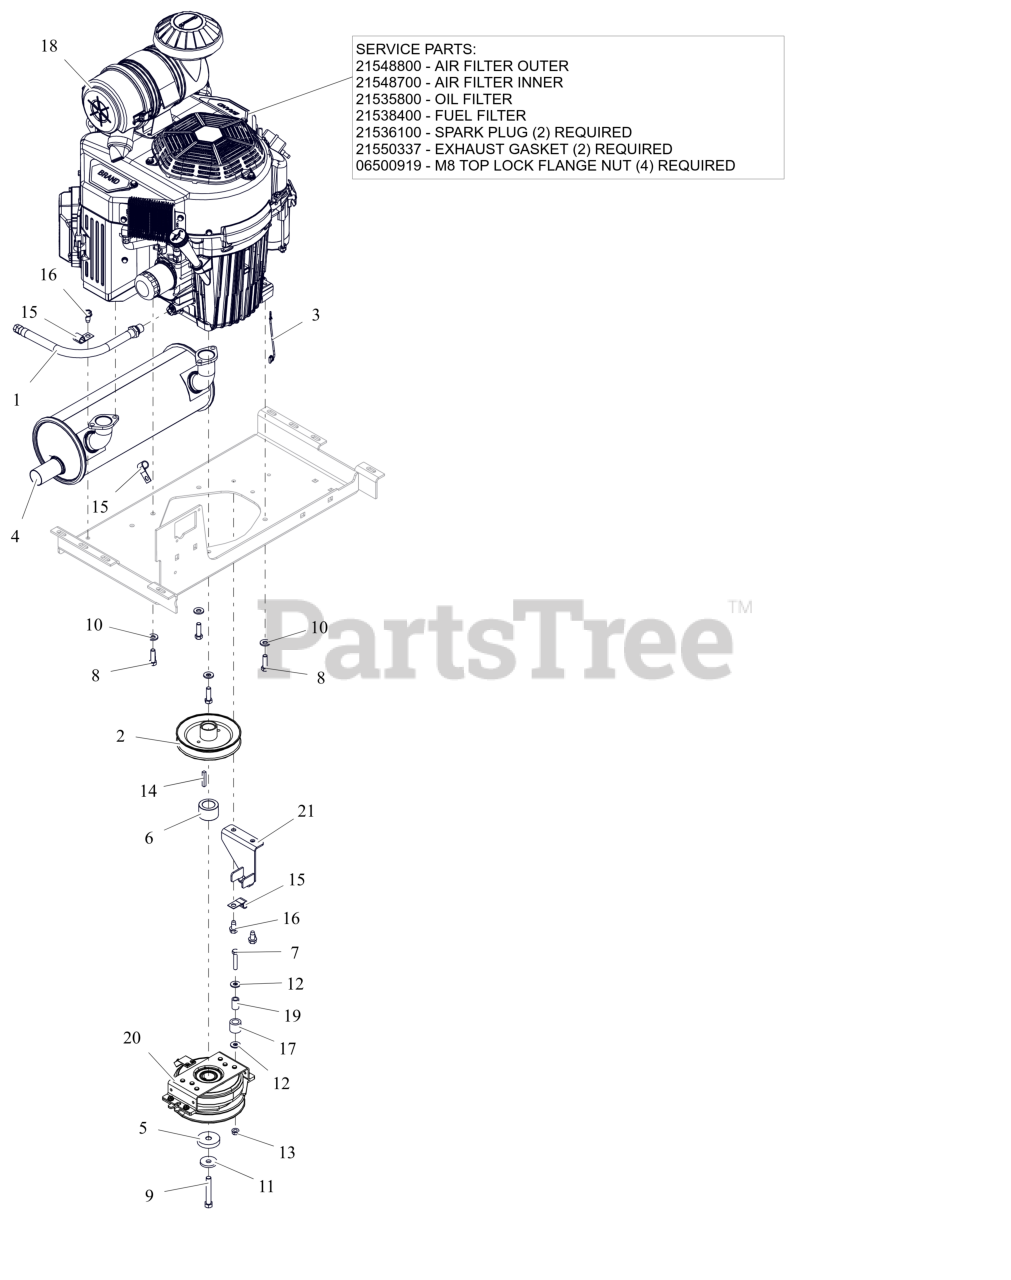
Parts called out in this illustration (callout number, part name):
1	HOSE, OIL DRAIN
2	WLDMT, TRANSAXLE DRIVE PULLEY
3	LEAD - STARTER SOLENOID
4	MUFFLER - 34HP KAWASAKI VERT.
5	SPACER, .450X2.00X.396
6	SPCR, 1.125 x 1.750 x 1.147
7	BLT, HEX .31-18X1.75 G5 ZCC
8	BLT, HEX .38-16X1.25 G5 ZCC NT
9	BLT, HEX 0.4375-20X2.75 G8 ZCC NT
10	WASHER, 3/8" SPRING DISC
11	WASHER, 7/16" SPRING DISK
12	WSHR,FLT .375X.875X.083 ZCC
13	NUT,LK-CTR-FLG .31-18 GF ZCC
14	KEY-SQ .25 X 1.50 X .25 SAE
16	SCR,TAP .375-16X.75 HWH TR ZCC
17	BUMPER,RUBBER .62X1.0X.88 LG
18	ENGINE-KAWASAKI FX921
18	FILTER, OUTER
18	FILTER, INNER - KAW
18	FILTER,OIL - KAW
18	FUEL FILTER - KAWASAKI
18	PLUG, SPARK
18	GASKET, EXHAUST (11061-7061)
18	NUT-LK-TOP-FLG M8 ZCC
19	BUSH.,S.391X.622X.950 ST
20	CLUTCH- OGURA GT2.75-DC03(D)
21	BRKT, CLUTCH STOP
